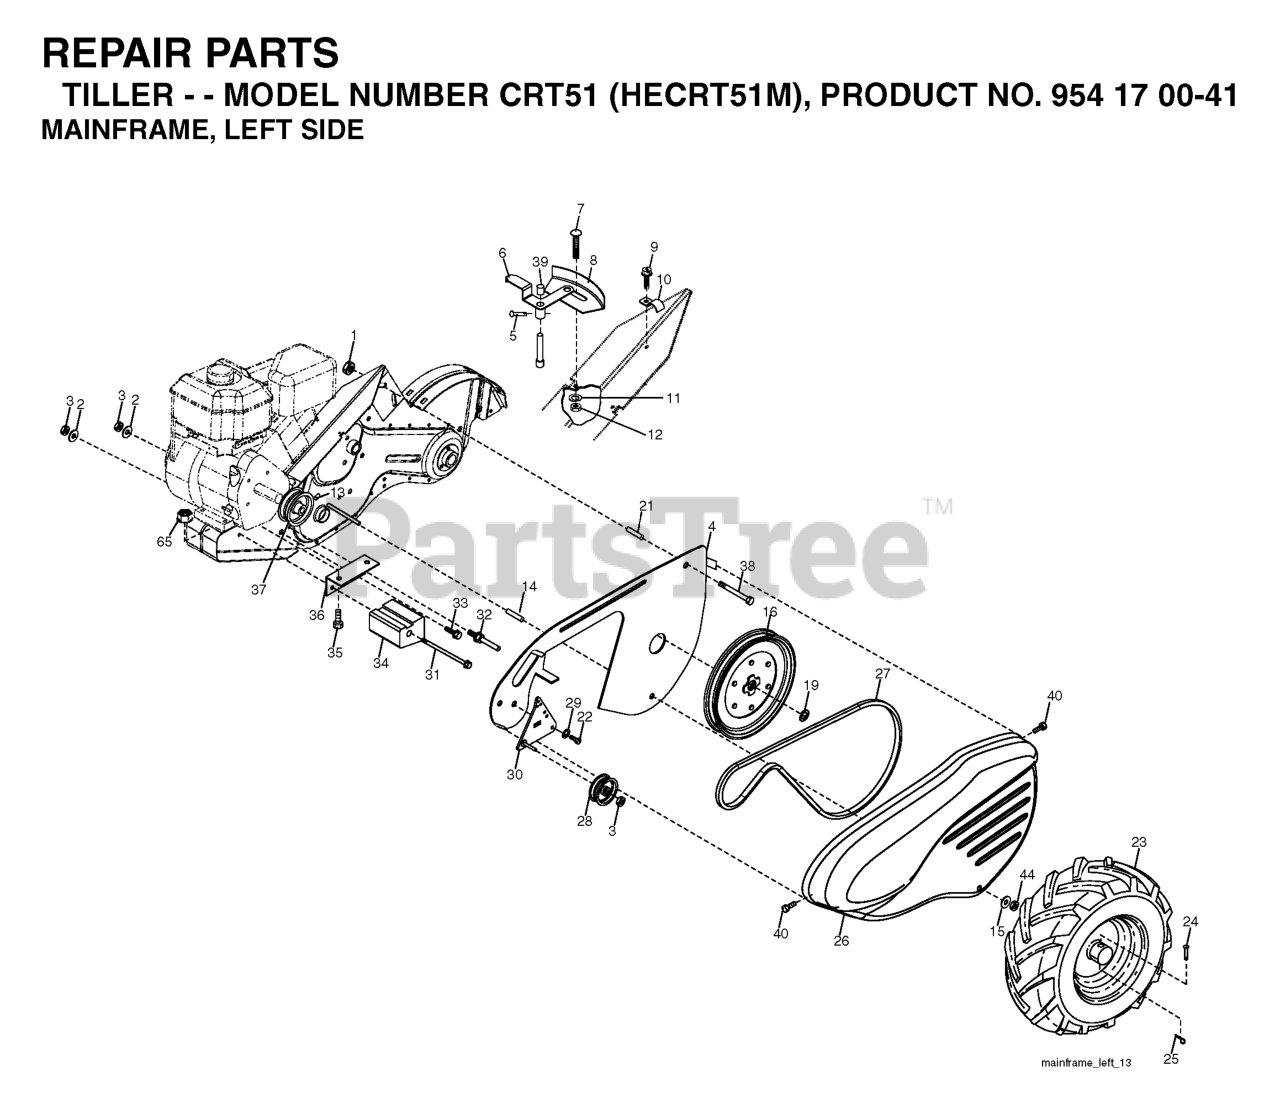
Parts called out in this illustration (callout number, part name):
1	NUT
2	WASHER, LOCK 3/8
3	NUT.HEX.3/8-16UNC
4	SHIELD
5	PIN.SPIROL.FLARED
6	LEVER ASM CRT
8	PANEL.INDICATOR.SHIFT.BLACK
9	TAPPING SCREW
10	CONDUIT.CLIP.PLATED
11	LOCKWASHER
12	NUT
14	SPACER-SPLIT.327 X .42
15	WASHER
16	SHEAVE, TRANSMISSION
19	RETAINING RING LT
21	SPACER CRT
23	TIRE.16X4-8.CHEVRON.TILLER
24	RIVET,DRILLED
25	RETAINER M
26	RP BELT GUARD
27	V-BELT
28	PULLEY-IDLER TI
30	BRACKET.ASM.IDLER.BLACK
31	BOLT.FIN.HEX.3/8-16UNC
32	SHIFT ARM CRT
33	BOLT
34	COUNTERWEIGHT.LH.CRT
35	Bolt Fin Hex 5/16 - 18 Unc x 2 Gr. 2
36	BRACKET LH CRT
37	RP.ENGINE PULLEY
38	BOLT
39	CAP.PLUNGER.BLACK
40	SCREW.HEX.WSH.SLT.#10-24X.50
44	NUT.71038.31-18.HEX.NYLOCK
65	LOCKNUT-FLANGE 5/16-18
